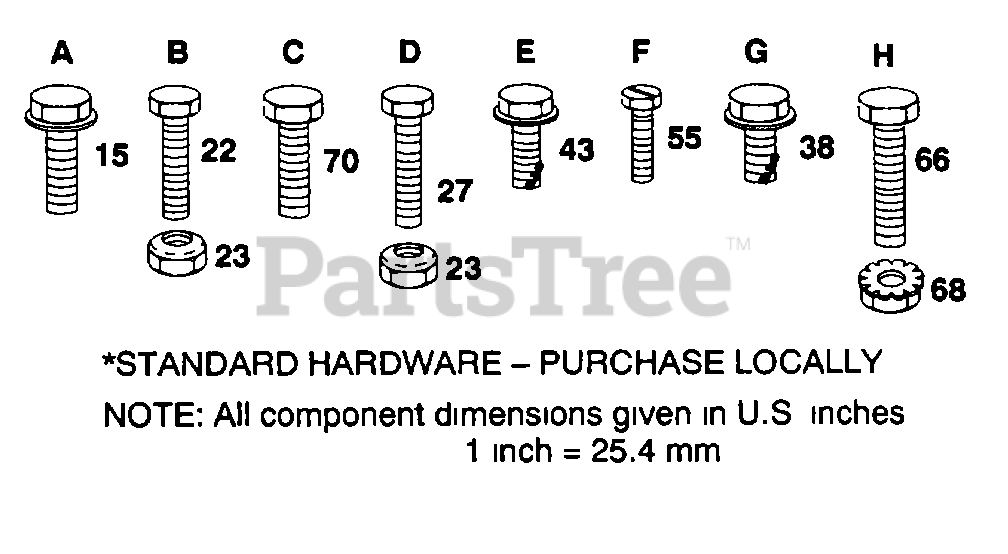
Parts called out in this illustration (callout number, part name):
15	SCREW SPECIAL
22	SCREW
27	BOLT
38	SCREW LT
43	SCREW LT
66	BOLT
68	NUT
70	SCREW
